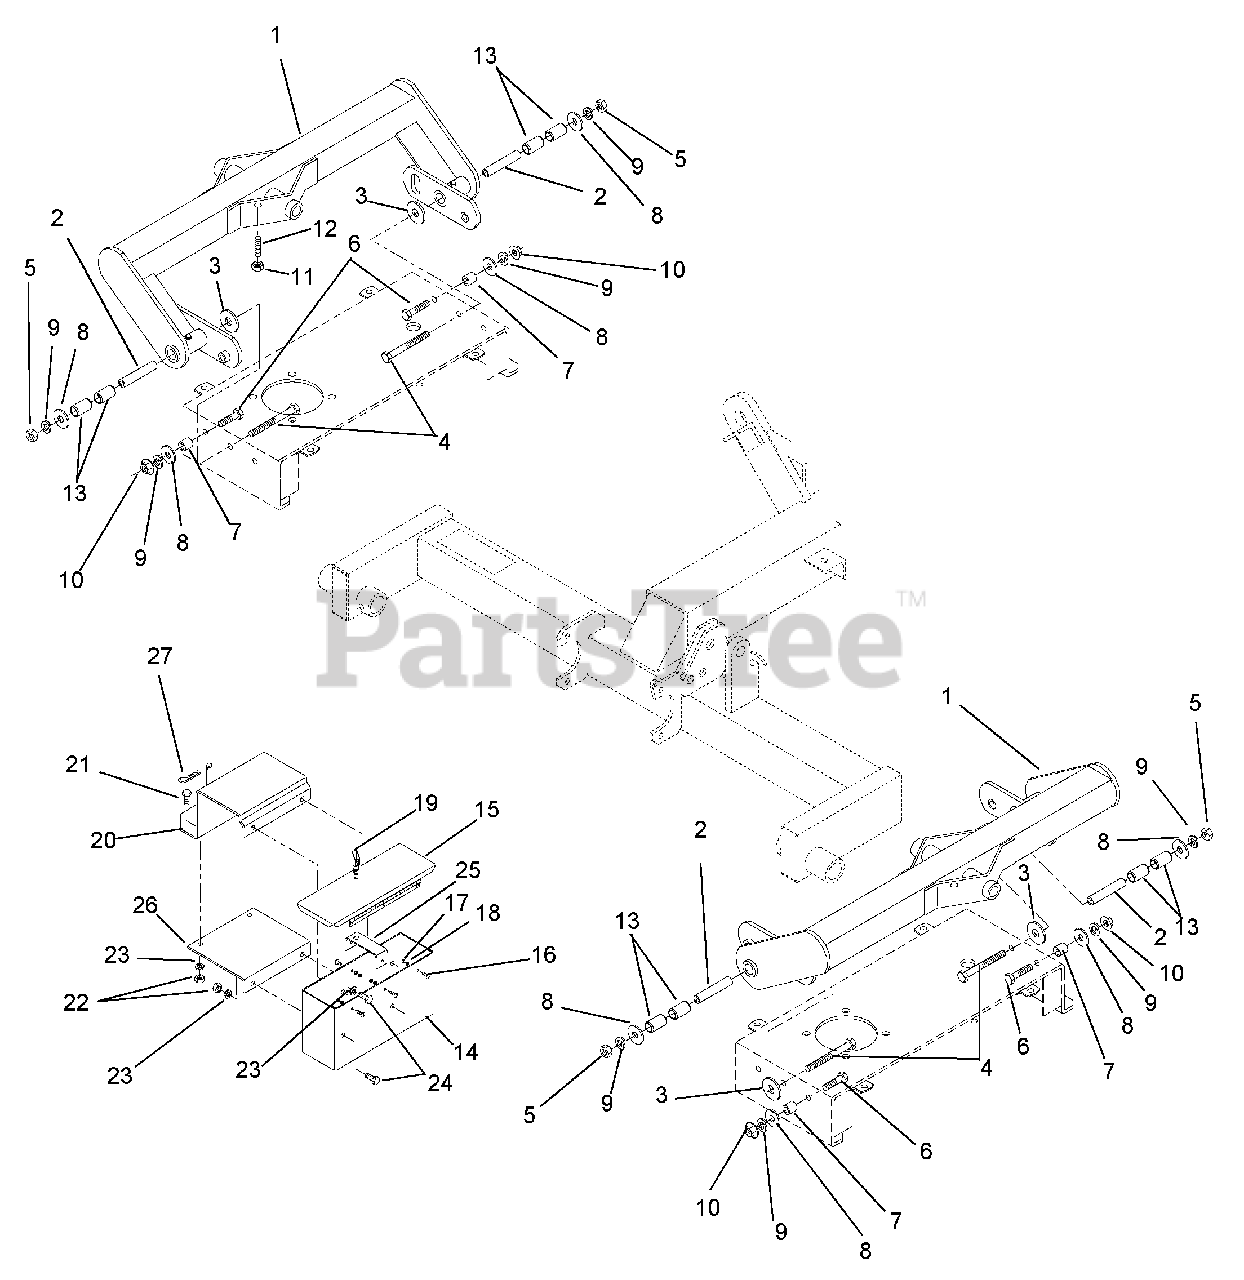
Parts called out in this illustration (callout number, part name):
1	Weldment, Deck Roll Bracket (Dick, painted part not yet in AS400)
2	Bushing, Wear
3	Washer, Heavy Duty Safety
4	Cap Screw, Hex Head .50-13 x 5.5
5	Nut, Lock .50-13
6	Cap Screw, Hex Head .50 x 2 Grade 8
7	Spacer, Limit
8	Washer, Flat .50 SAE
9	Washer, Lock .50
10	Nut, Hex .50
11	Nut, Jam .50-13
12	Screw, Set .50-163 x 1.75
13	Bushing, Spring 1 x 1.75 x 1.75
14	Weldment, Box
15	Weldment, Top
16	Screw, Slotted Pan Head Machine #10 x .50
17	Nut, Hex #10
18	Washer, Lock #10
19	Latch, Swell
20	Bracket, Upper Tool Box Mounting
21	Cap Screw, Hex Head .38-16 x .75
22	Nut, Hex .38-16
23	Washer, Locking .38
24	Cap Screw, Hex Head .38 x .75
26	Bracket, Lower Tool Box Mounting
27	Pin, Presto Spring Clip 9 G
